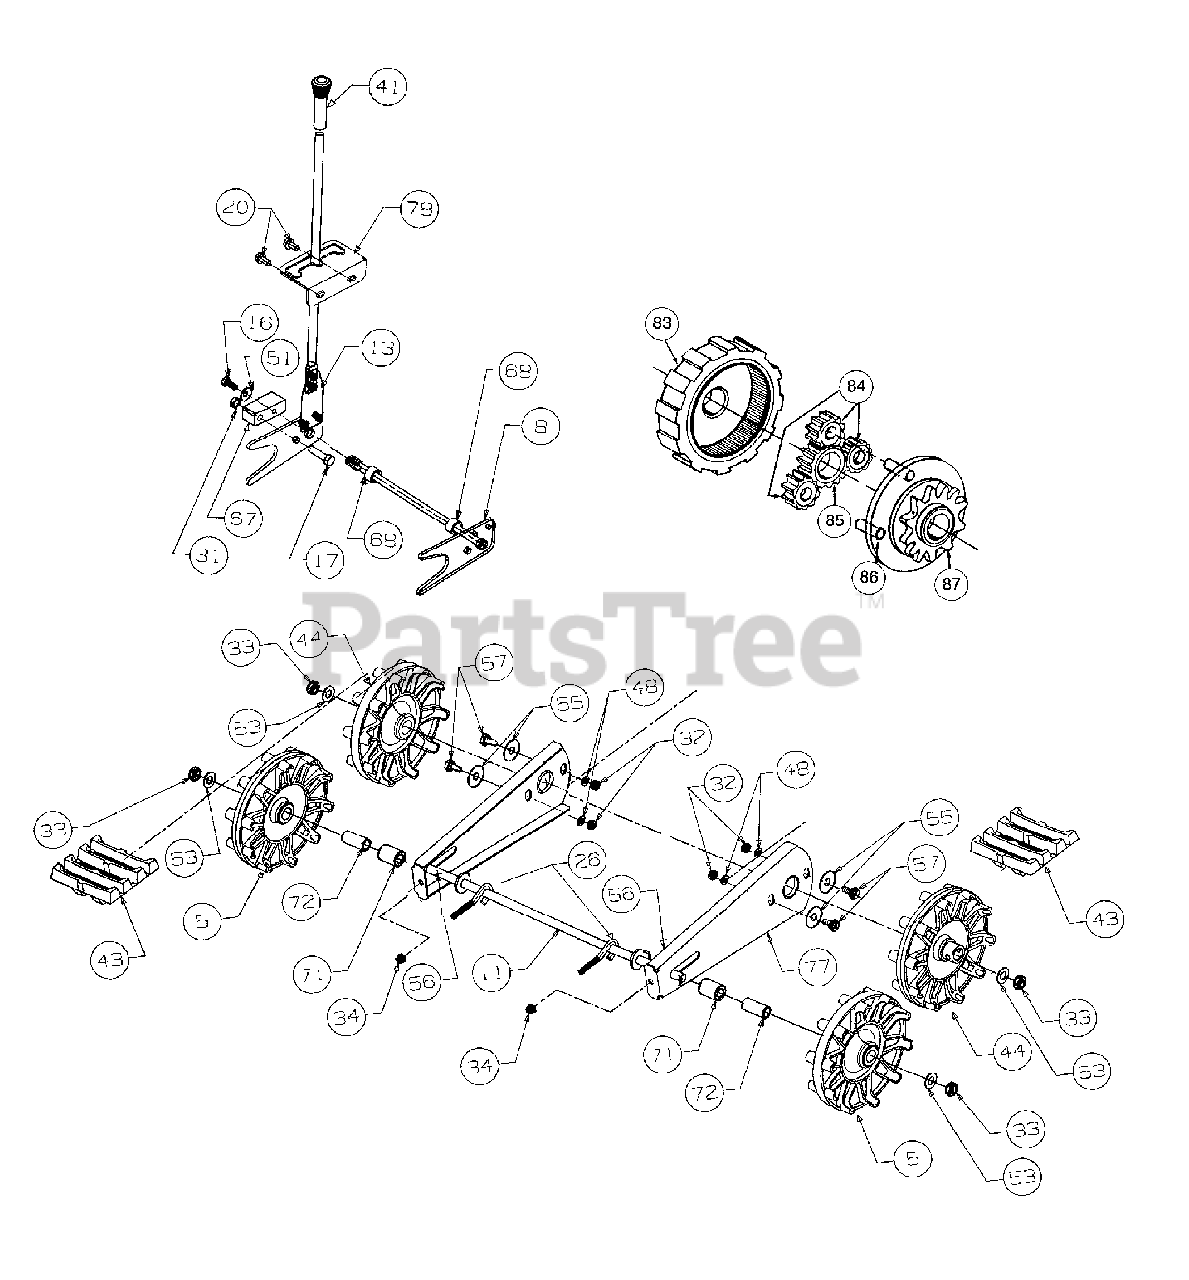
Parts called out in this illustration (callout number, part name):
5	Wheel Assembly Idler
16	Screw
17	Screw
20	Screw
26	Screw
31	Nut Lock
32	Nut Hex
33	Nut Jam
34	Nut Hex
43	Track
44	Wheel-Track Drive
48	Washer - Lock
51	Washer - Bell
53	Washer - Flat
55	Washer - Flat
56	Lubricant
57	Screw - Shoulder
58	Screw - Shoulder
67	Lift-Shaft Drive
68	Spacer
71	Spacer
72	Spacer
83	Gear Ring
84	Gear 12-Tooth
85	Gear 18-Tooth
86	Pin Dowel
87	Carrier
